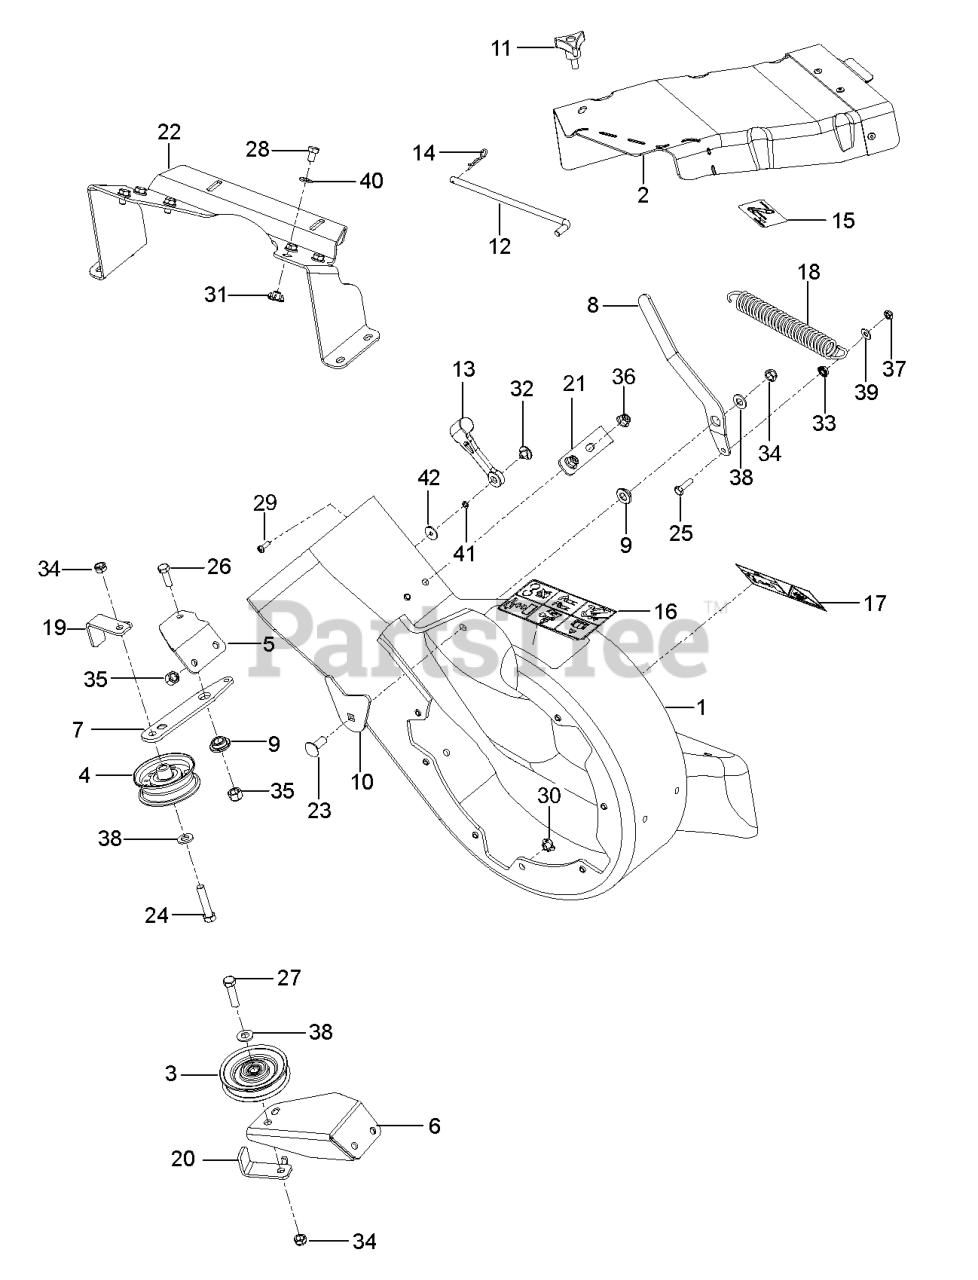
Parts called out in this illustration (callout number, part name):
1	BLOWER.HOUSING.W/DECALS.COLLEC
5	MOUNT.IDLER.UPPER
6	MOUNT IDLER LOWER
8	ARM, TENSION
10	SCREW
11	KNOB W/STUD
12	PIN, RETENTION
13	HOOD LATCH
14	HAIRPIN #2
15	DECAL, BELT ROUTING
16	DECAL, EURO WARNING
17	EURO DECAL, IMPELLER
19	KEEPER FLAT UPPER BLK
20	KEEPER FLAT LOWER BLACK
22	BRACKET.MOUNT.BLACK
23	BOLT D
24	BOLT, HCS 3/8-16X1-3/4
25	BOLT
26	BOLT.FIN.HEX.5/16-18UNC X 1.00
27	BOLT
28	HCS 5/16-18 X 1/2 GR 5 ZD
29	SCREW #10-24 X 5/8
30	NUT 1/4-20 TEE
31	NUT 5/16-18 TEE
32	NUT 10-24 WELD PLATED
33	NUT.FLANGE.1-4-20-SERR
34	NUT HEX 3/8-16 NYLON, THIN
35	NUT.71038.31-18.HEX.NYLOCK
36	5/16-18 NYLOC FLANGE NUT
37	JAM NUT 1/4C (2 2 PW01)
38	WASHER
40	WASHER
41	WASHER - 3/16 LOCK ZD
